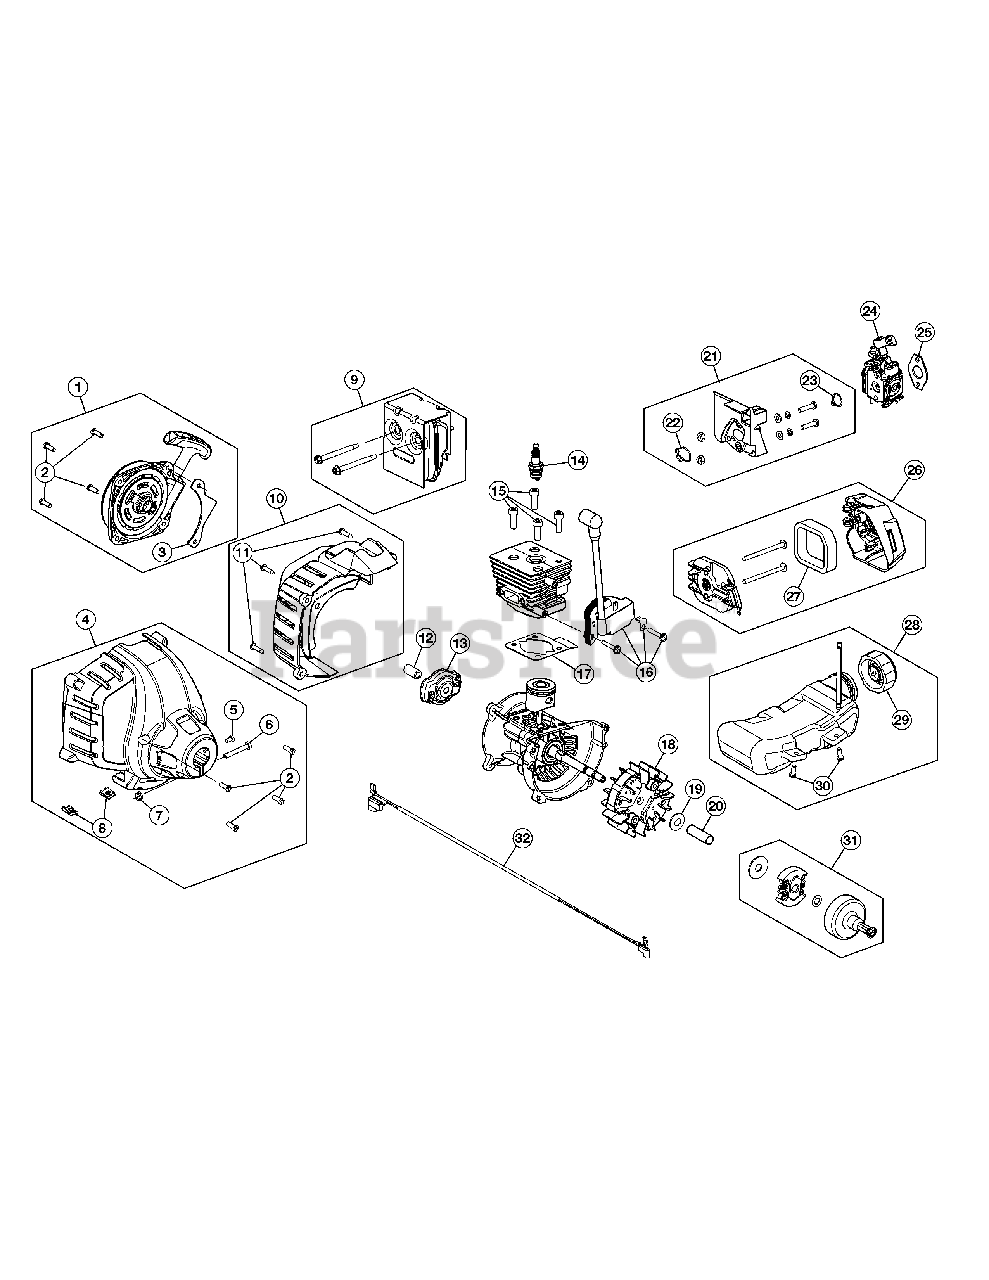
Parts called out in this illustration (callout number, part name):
1	Starter Assembly (Incl. 2 & 3)
2	Starter Screw
3	Starter Assembly Guard (Incl. 2)
4	Clutch Cover Assembly (Incl. 2 and 5 - 8)
5	Anti-Rotation Screw
6	Clamp Screw
7	Clamp Nut
8	U-shaped Nut
9	Muffler Assembly
10	Rear Engine Cover (Incl. 11)
11	Cover Screw
12	Adapter
13	Pawl Assembly
14	Spark Plug
15	Cylinder Bolt
16	Module Assembly
17	Cylinder Gasket
18	Flywheel Assembly
19	Washer
20	Spacer
21	Insulator Assembly (Incl. 22 and 23)
22	Insulator O-Ring
23	Carburetor O-Ring
24	Carburetor
25	Carburetor Gasket
26	Air Cleaner Assembly (Incl. 27)
27	Air Cleaner Filter
28	Fuel Tank Assembly (Incl. 29 and 30)
29	Tank Fuel Cap
30	Fuel Tank Screw
31	Clutch Assembly
32	Lead Wires
